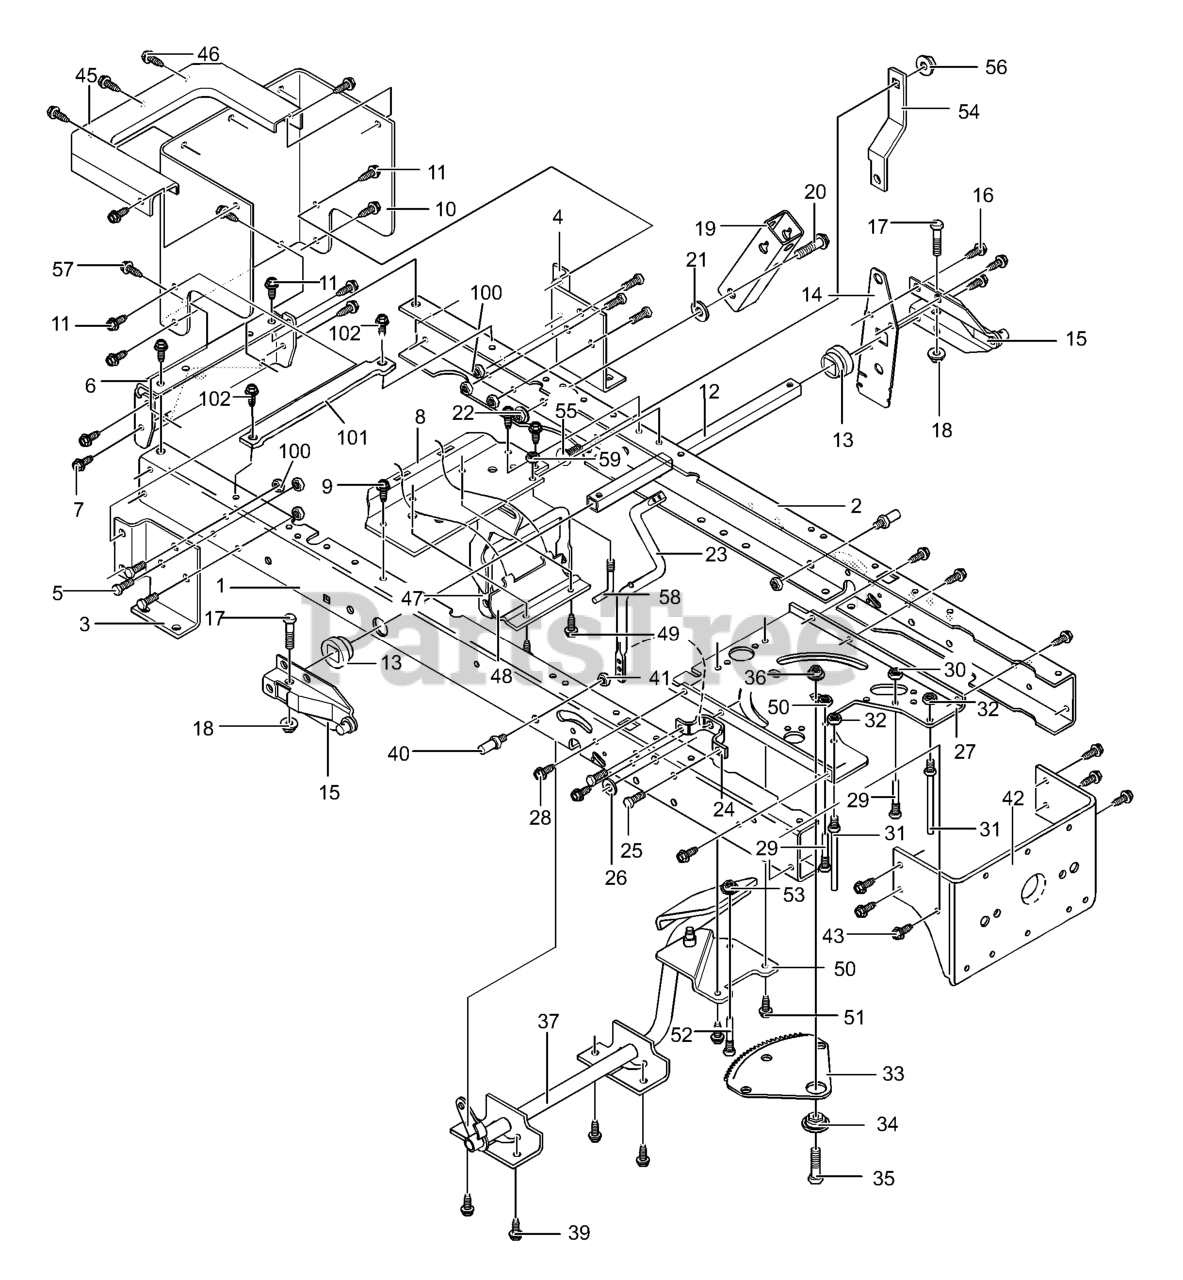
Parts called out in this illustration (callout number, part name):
1	Frame, Rail RH
2	Frame, Rail LH
3	Bracket, Transaxle RH
4	Bracket, Transaxle LH
5	Screw, .312-18x.75
7	Screw , .312-18x.75
8	Bracket, Idler/Trunnion
9	Screw , .312-18x.75
10	Plate, Rear
11	Screw , .312-18x.75
12	Lifter Tube
13	Bushing, Lift Arm
14	Plate, Lift Arm
15	Lever, Lift Arm
16	Screw .31x.50
17	Screw, .5/16-21x1.25
18	Nut, .32-24 Flangelock
19	Pivot Bracket
20	Bolt, 3/8 HHSH
21	Flat washer
22	Nut, .38-16 Flange Ctrlk
23	PTO Crank
24	Bracket, Bell Crank
25	Screw, .312-18x.75
26	Flat washer
27	Steering Plate
28	Screw, .312-18x.75
29	Screw Guide 5/16-18
30	Nut, .32-18 Flangelock
31	Screw Guide
32	Nut, .32-18 Flangelock
33	Gear Sector
34	Bearing, Sector Gear
35	CAPSCREW, Hex Head, 5/16-18 x 1
36	Nut, 5/16 Hkeps
37	Cl/Br Pedal Dlx
39	Screw, .312-18x.75
40	Pin, Threaded Shoulder
41	Nut, 3/8-16 Hwdfl Whiz
42	Bracket, Hanger Rear
43	Screw, .312-18x.75
45	Top, Rear Plate
46	Screw, Thread Form
47	Yoke Assy., Trunnion
48	Clamp, Trunnion
49	Screw, 5/16-18 x 0.75
50	Idler, Intermediate
51	Screw, 5/16-18 x 0.50
52	Screw Guide 5/16-18
53	Nut, .32-18 Flangelock
54	BRACKET, Torque Strap, LH
55	Bolt, CRG .31-18x0.62
56	Nut, .32-18 Flng Ctrlk
57	Engine Bolt, 3/8x1.25
58	Screw Guide
59	Nut, .32-18 Flangelock
100	Nut, .32-18 Flang Centerlock
101	Brkt, Battery Support
102	Screw, 5/16-18 x 0.75
